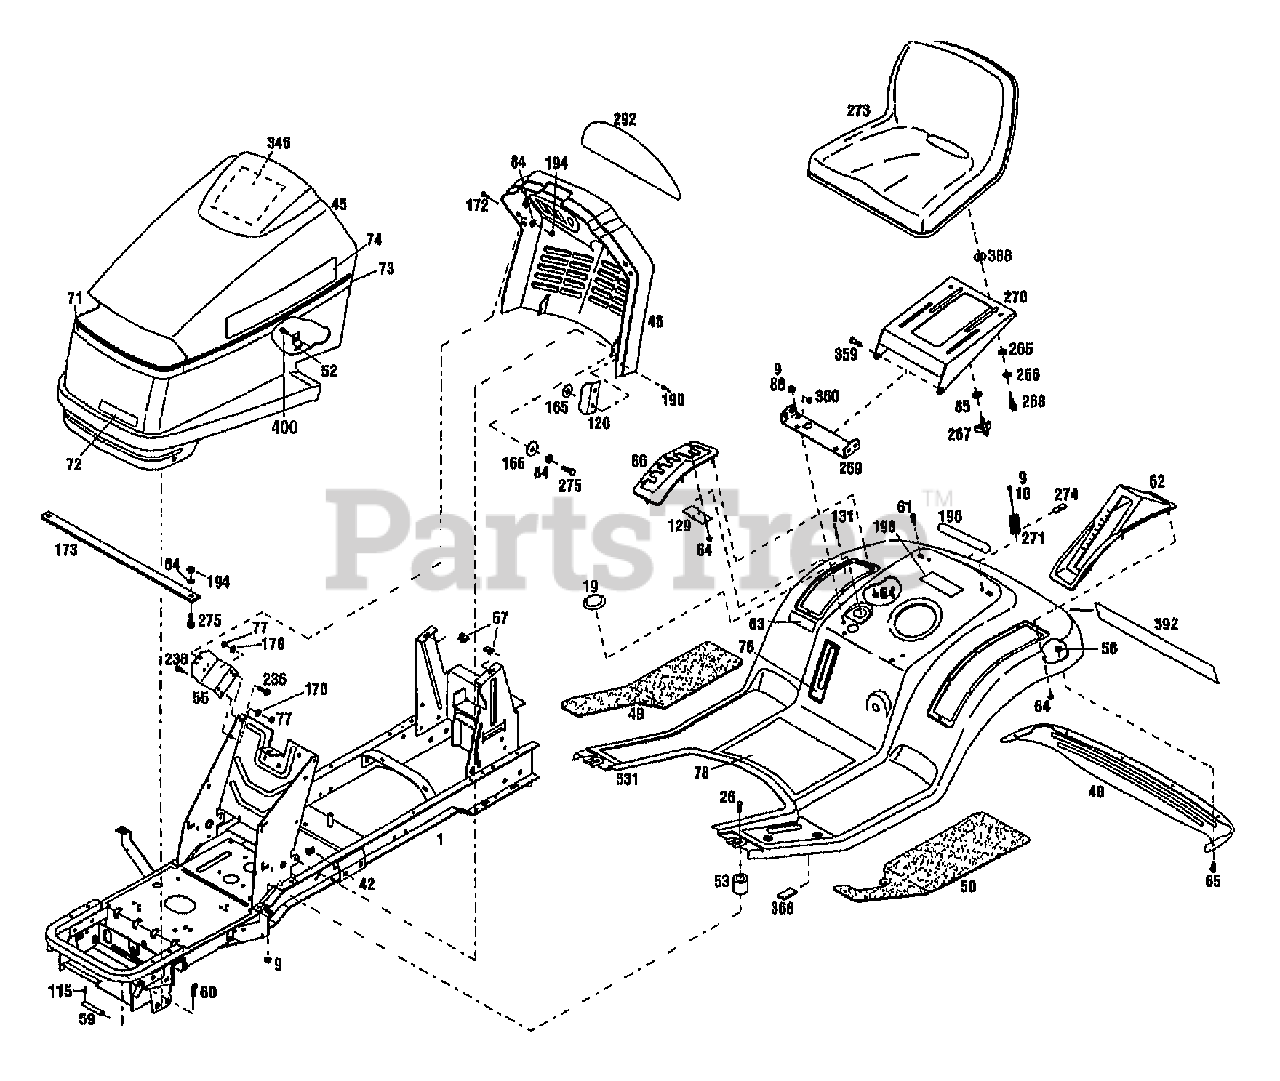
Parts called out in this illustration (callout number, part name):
1	ASSM-FRAME LTX
9	NUT-HFLK 5/16-18 ZP
10	SCR-HHC 5/16-18X.75 GR 5 ZP
19	PLUG 2.50
26	SCR-CARR 5/16-18X1.0 G2 ZP
42	NUT-SPEED
45	HOOD-TRACTOR
48	TRIM-FENDER REAR
49	PAD-FOOT RH
50	PAD-FOOT LH
52	LATCH
53	SPACER-TUBULAR
55	BRKT-MOUNTING
56	NUT-HF/LK 1/4-20 ZP
57	NUT-SELF RETAIN 5/16-18
59	PIN-PIVOT HOOD
60	PIN-HITCH .125X2.56 ZP
61	SCR-LOCK
62	COVER-LIFT HANDLE
63	DECAL-AMERICAN LEGEND-LRG
64	NUT-SELF THREADING
65	SCR-HH 1/4-20X.625
66	QUADRANT-SHIFT
71	DECAL-STRIPE HOOD FRONT
72	DECAL-LOGO
73	DECAL-STRIPE SIDE
74	DECAL-LOGO TROY-BILT
76	DECAL-FUEL LEVEL
77	NUT-HEX 5/16-18 ZP
84	WASHER-LK .25 ZP
85	WASHER-FLAT 3/8 SAE
88	SCR-CARR 5/16-18X.62 G2 ZP
115	PIN-ROLL .188X1.0
120	BRKT-HOOD ALIGN
129	SUPPORT-SHIFT ARM
131	RIVET-POP .125
165	WASHER-.88X.2X.059
166	WASHER-FLAT 1.25X.28X.062 ZP
170	WASHER-LK .312 ZP
173	STRAP-HOOD
190	RIVET-POP
194	NUT-HEX 1/4-20 ZP
196	DECAL-LOGO FENDER
198	DECAL-FUEL
236	SCR-HFLK 5/16-18X.75 ZP
265	WASHER-1.06X.51X.09 NYLON
266	WASHER-BOW .74X.52X.01
268	SCR-SHLDR 3/8-16X.25 G5ZP
269	BRKT-SUPPORT SEAT
270	SUPPORT-SEAT
271	SPRING-COMPRESSION
273	KIT-SEAT (TRACTOR)
274	BRKT-SPRING HOLD DOWN
275	SCR-HH 1/4-20X.625 G5 ZP
292	LENS-INSTRMTS WARN LIGHTS
346	DECAL-SERVICE
359	SCR-HH 3/8-16X.88 G5 ZP
360	NUT-H/LK 3/8-16
388	WASHER-FLAT
392	DECAL-MODEL
531	FENDER-RED W/DECALS
